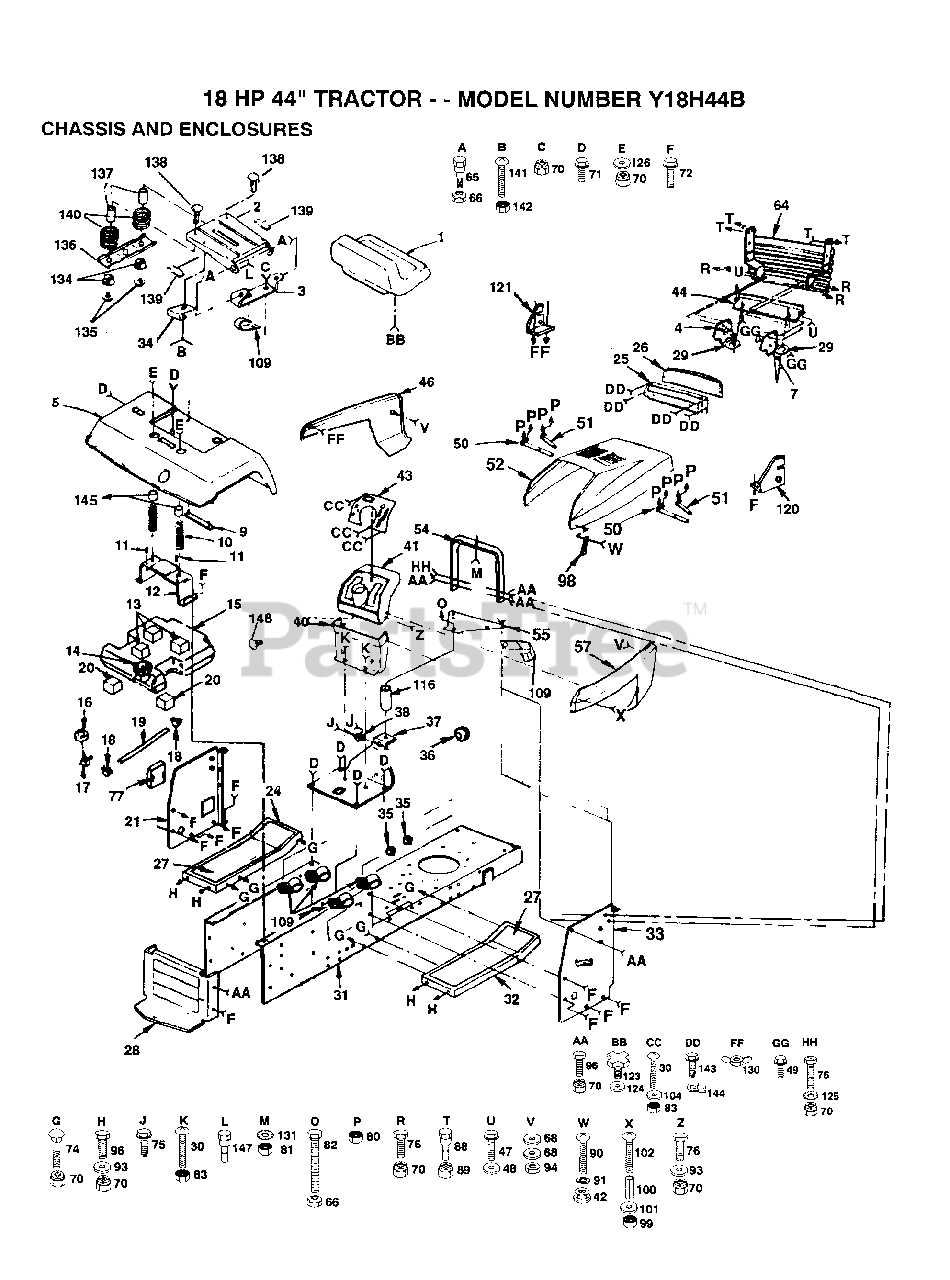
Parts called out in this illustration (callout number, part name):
4	SUPPORT LH YTH
5	FENDER
7	SUPPORT RH YTH
10	SPRING COMPRESSIO
11	NUT-PUSH YT
13	PAD-SPACER LT
16	BUSHING OUTLET T
17	FUEL TANK STEM GT
18	HOSE CLAMP
20	PAD IDLER TI
21	PANEL DASH LH
26	LENS LT
27	FOOTREST PAD
28	DRAWBAR LT/YT
29	WASHER
30	SCREW
33	DASH PANEL RH
36	SNAP BUSHING T
40	LOWER DASH
42	WELDNUT
47	SCREW
48	WASHER
49	SCREW
54	SUPPORT ASS'Y
57	"PANEL,SIDE RH "
68	WASHER PM
71	SCREW LT
72	SCREW
74	BOLT
76	BOLT
77	COVER ACCESS
80	NUT
82	BOLT
90	SCREW
91	LOCKWASHER
93	WASHER
98	HOOD LATCH T
100	SPACER LT
101	WASHER
102	SCREW
104	WASHER
109	CLIP T
116	SPACER
120	SUPPORT RH YTH
121	SUPPORT LH YTH
123	"KNOB 1/2"" YT"
124	WASHER
125	LOCKWASHER
126	WASHER
134	BUSHING
136	BRKT SWITCH
137	SPACER SPLIT
139	STRIP FORM
140	SPRING COMPRESSED
142	"NUT,KEPS"
144	"""J"" FASTENER LT"
145	CAP SPRING
147	"BOLT,SHOULDER"
148	PLUG BUTTON T
